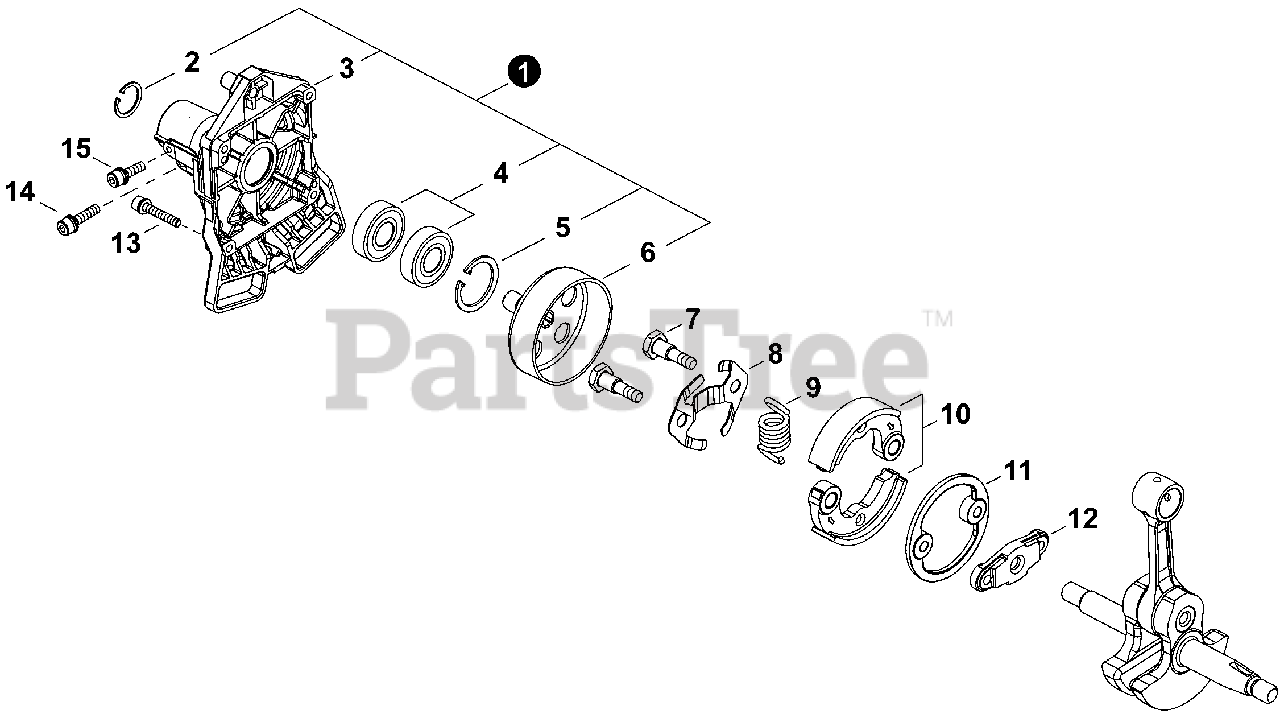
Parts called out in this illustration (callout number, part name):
1	CASE ASSY, CLUTCH
2	RING, SNAP 12
3	CASE, CLUTCH
4	BEARING, BALL
5	RING, SNAP 28
6	DRUM, CLUTCH
7	BOLT, CLUTCH
8	SPRING, FLAT
9	SPRING, CLUTCH
10	CLUTCH SHOE SET
12	HUB, CLUTCH
13	BOLT, TORX 5x25
14	BOLT, TORX 5x20
15	BOLT, TORX 5x10
